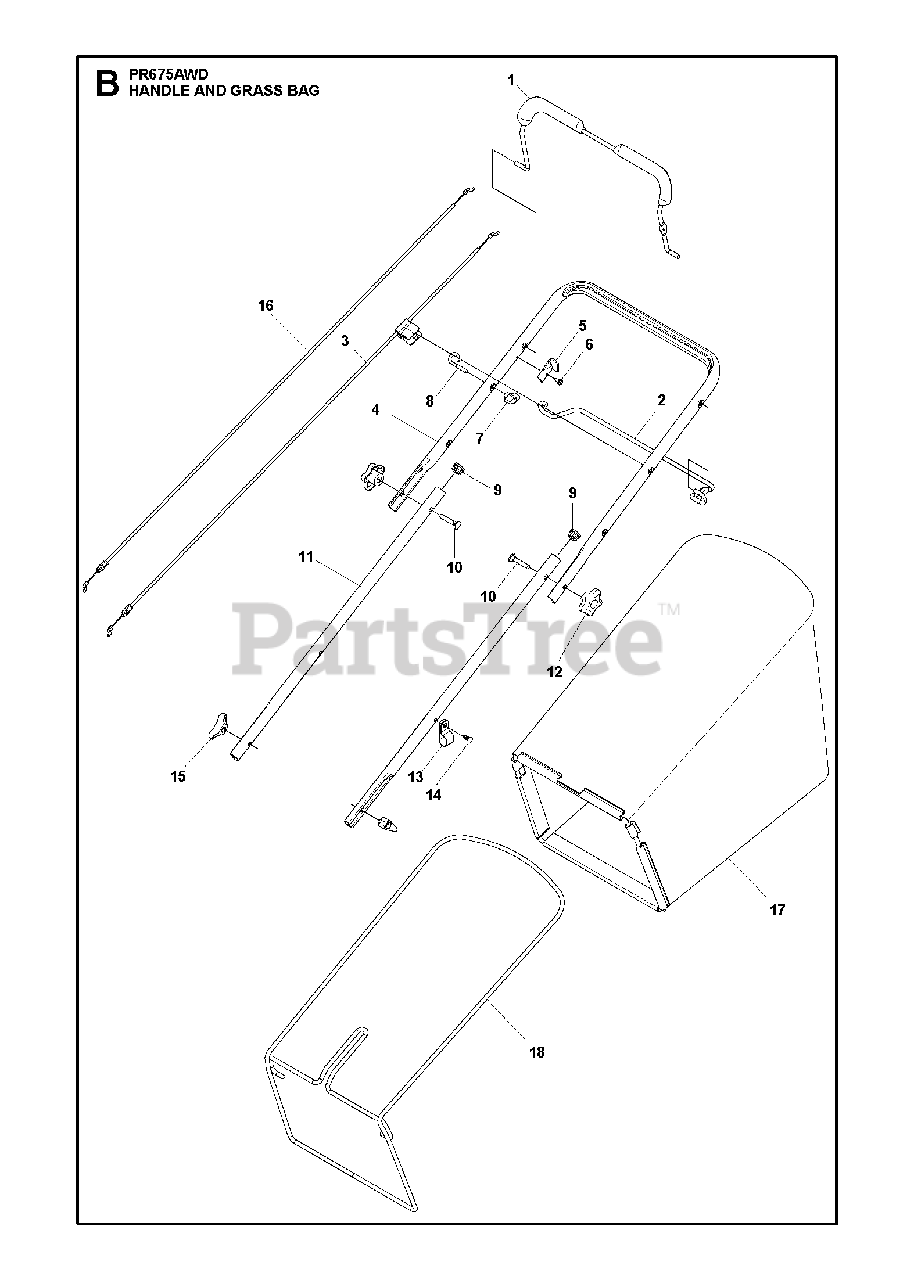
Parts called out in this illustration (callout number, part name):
1	Bail, Om Strt Mzr Marig 421
2	BAIL.DRIVE.S/S.ROUND.MARI.21
3	Cable, MZR Dual 5 95Ext45 92Con
4	HANDLE.UPP.DST.EXCR.SM.SP.479
5	BRACKET.UPSTOP.RT
6	SCREW
7	T-KNOB.NEW ROPE GUIDE
8	Rope Guide, Blk Zinc Chrom
9	PLUG.PLASTIC.7/8".14-20.GAUGE
10	Retaining Bolt, Concave Head
11	Lower Handle, 2Pc 2-Position
12	KNOB.HANDLE.PLASTIC.STAR.BLACK
13	CLIP.CABLE.BLK
14	FASTENER.PUSH.O.250X0.783
16	Drive Cable, Up Na21
17	Grass Bag Assembly, 2.3 Cu Ft
18	Grass Bag Frame, Awd 21 Black
